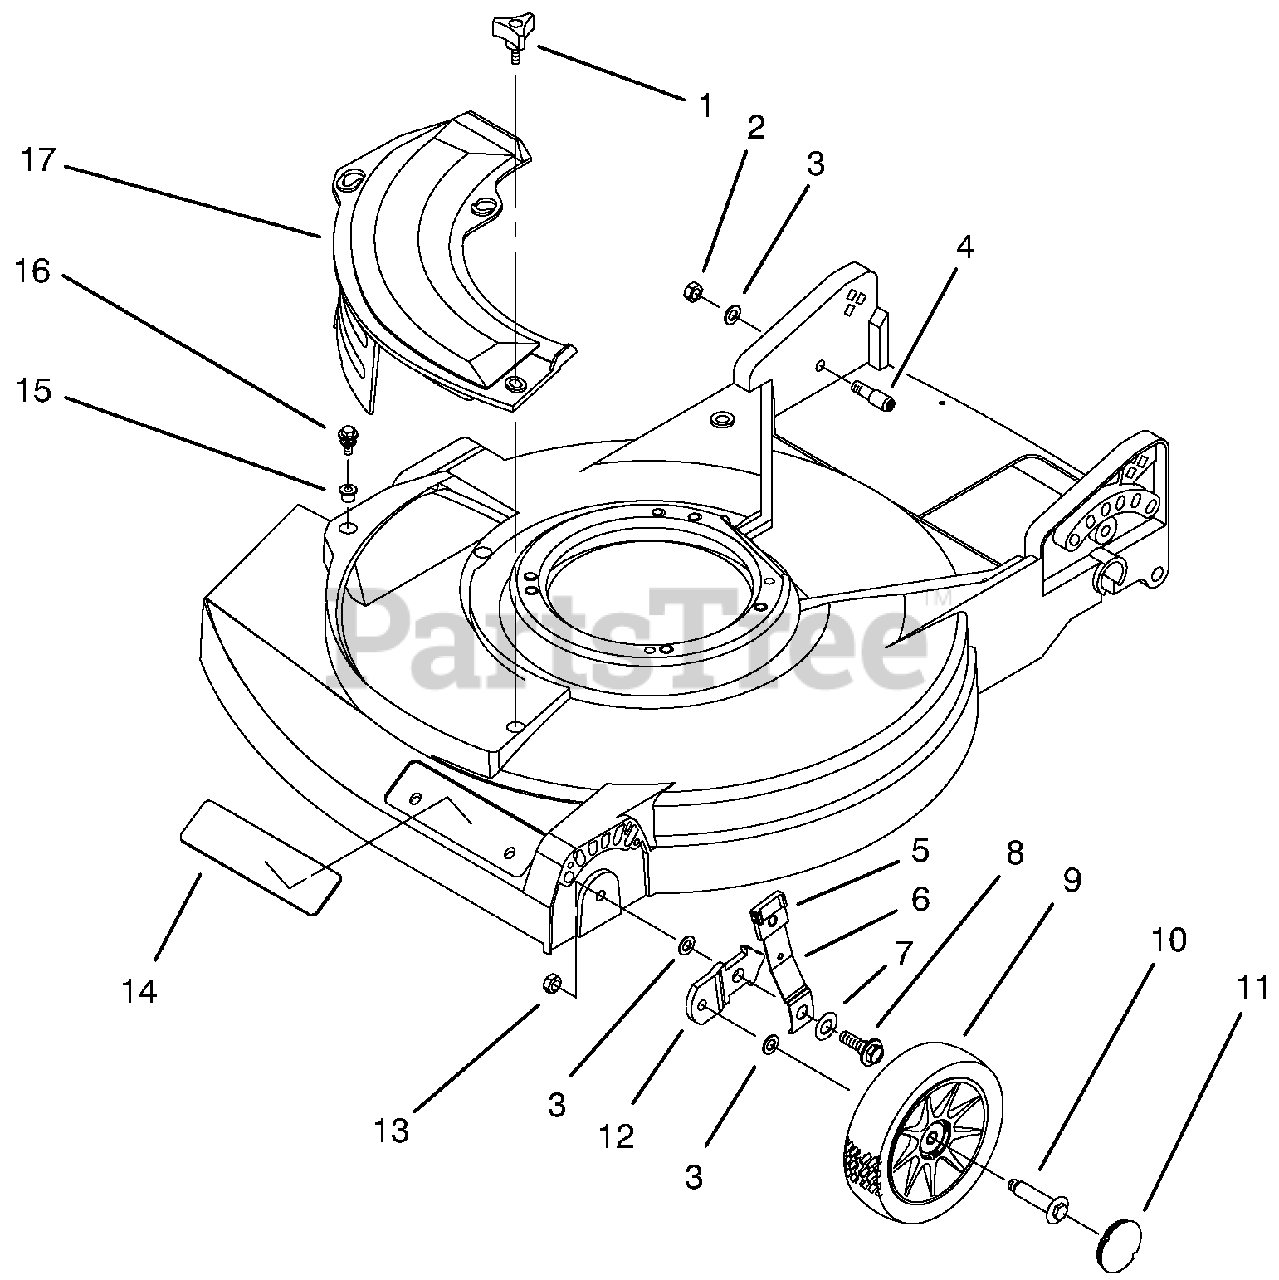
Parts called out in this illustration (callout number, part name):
1	Knob-Cover Plate
2	Nut-Lock
4	Bolt-Shoulder
5	Knob-Height Adjust
6	Spring Arm Ass'y-Front
7	Washer-Belleville
8	Bolt-Shoulder
9	Wheel & Tire Assembly 6"
10	Bolt-Shoulder
12	Bracket-Wheel Height Adj.
13	Nut-Lock
14	Housing-Applique
15	Grommet
16	Screw-Sems Thr'd Form.
17	Plate-Mulch
